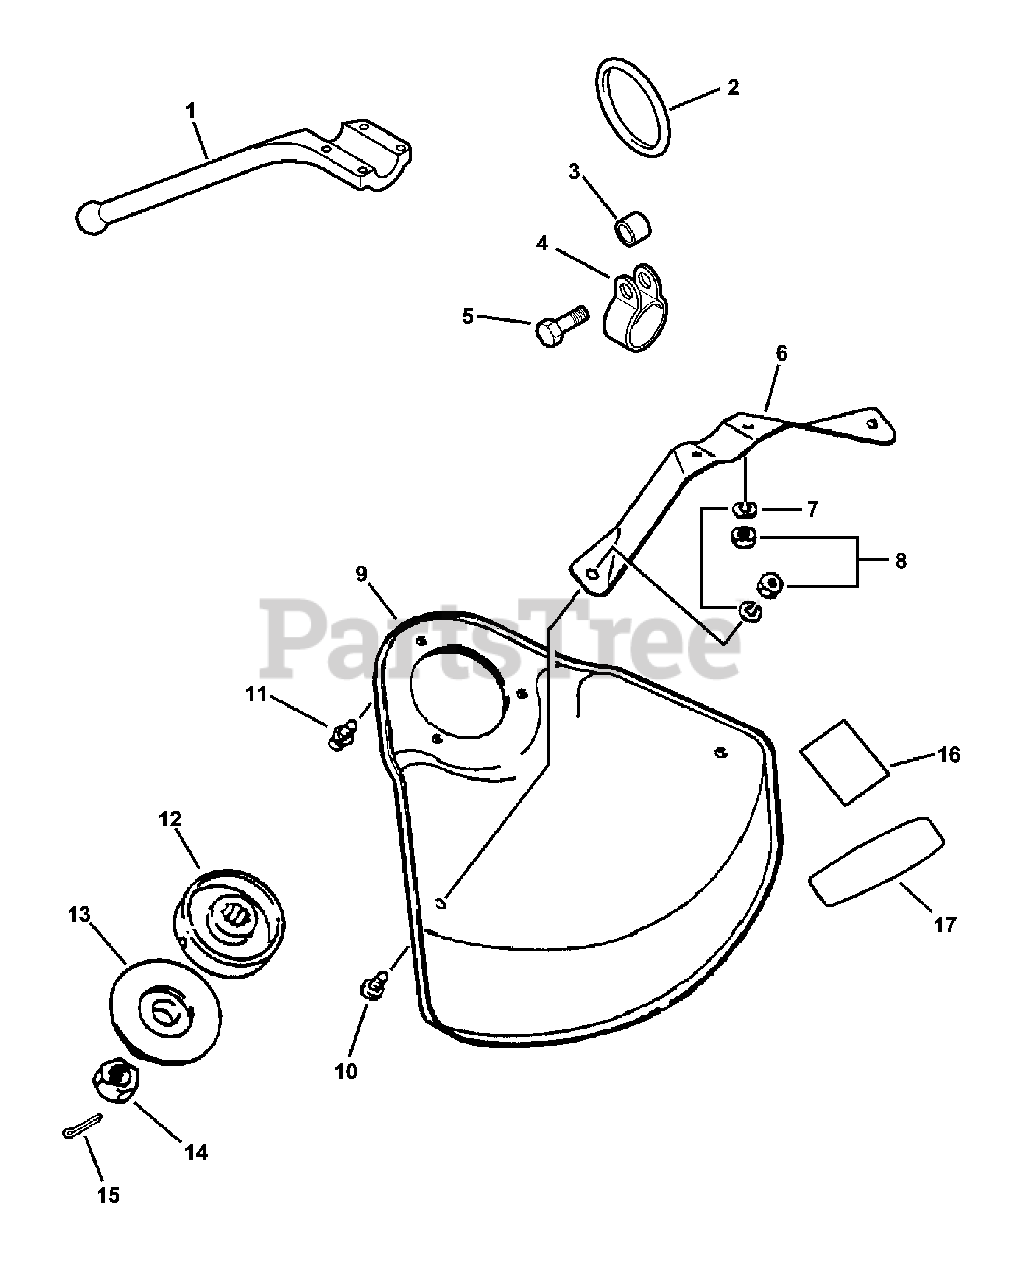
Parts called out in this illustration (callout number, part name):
1	BAR, BARRIER
5	BOLT - 5X18
6	BRACKET, SHIELD
7	LOCKWASHER - 5
9	SHIELD, DEBRIS - METAL
10	SCREW - 5X8
11	SCREW - 5X10
12	ADAPTOR, BLADE - UPPER
13	ADAPTOR, BLADE - LOWER
14	NUT - 10 -- LEFT HAND
15	PIN, SPLIT - 2X22
16	LABEL - ECHO
17	LABEL - DANGER
